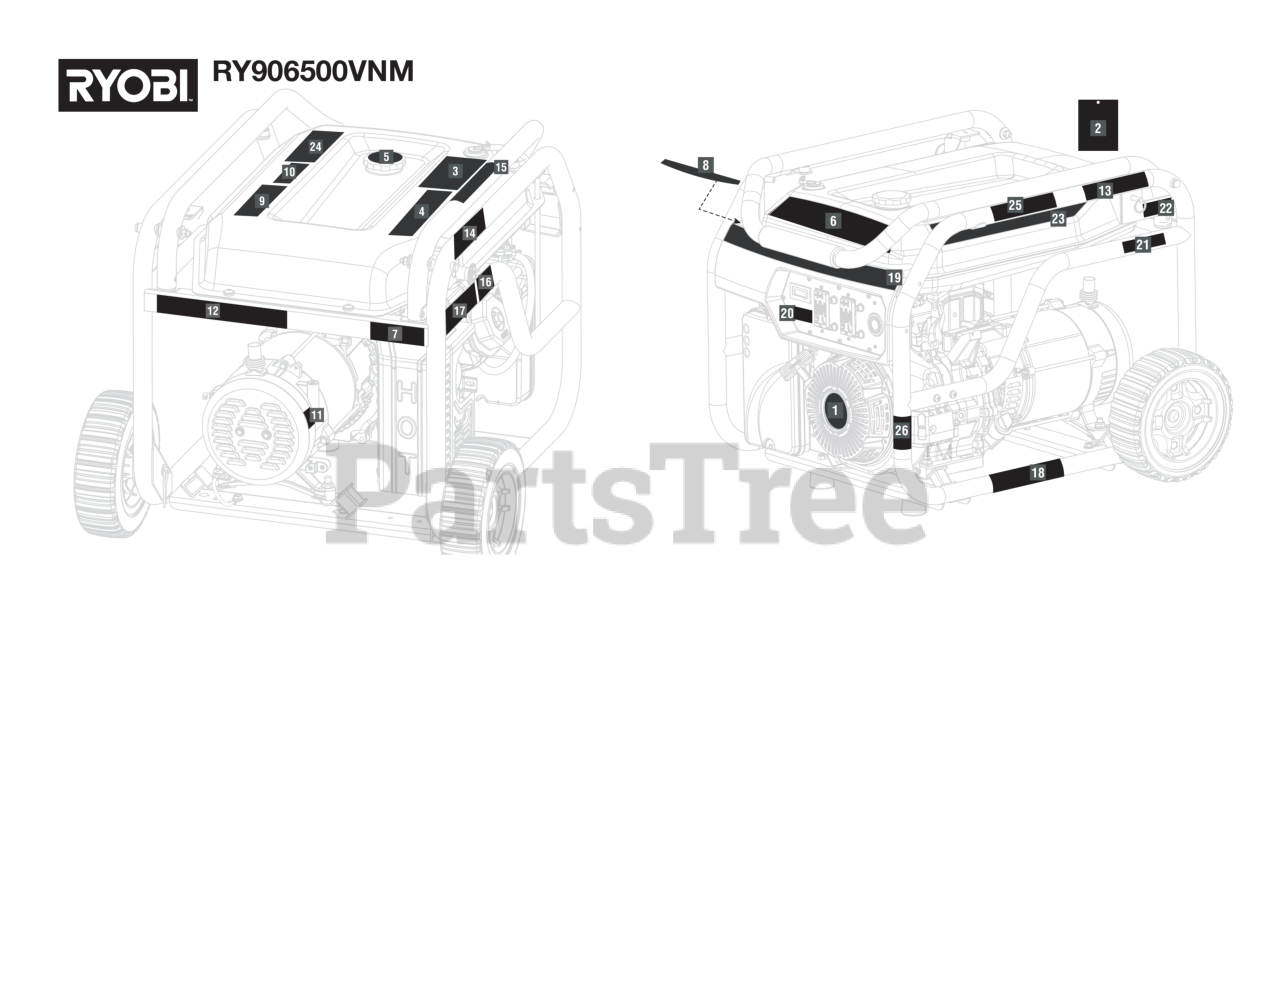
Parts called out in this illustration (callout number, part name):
1	Engine Recoil Label
2	Warning Hangtag
3	Warning Label
4	CPSC (English) Label
5	Remove Cap Fuel Stabilizer Label (English)
6	Logo Label
7	Combustion Label
8	Start Label
9	Fuel Stabilizer Label (French/Spanish)
10	No E85 Label
11	Ground Label Icon
12	Ground Warning Label
13	Risk of Fire Danger Label
14	Quick Release Pin Label
15	Exhaust Direction Label
16	Hot Surface and Exhaust Label
17	Fire Distance Label (Eng/Sp)
18	Engine Lubricant Label
19	Performance Label
20	Choke Label
21	Inquires Label (Ryobi)
22	Lock Pin Label
23	Auto Shut-Off Label
24	Co Instruction & Warning Label
25	CO Detect Logo Label
26	Do Not Tamper Label (FR)
